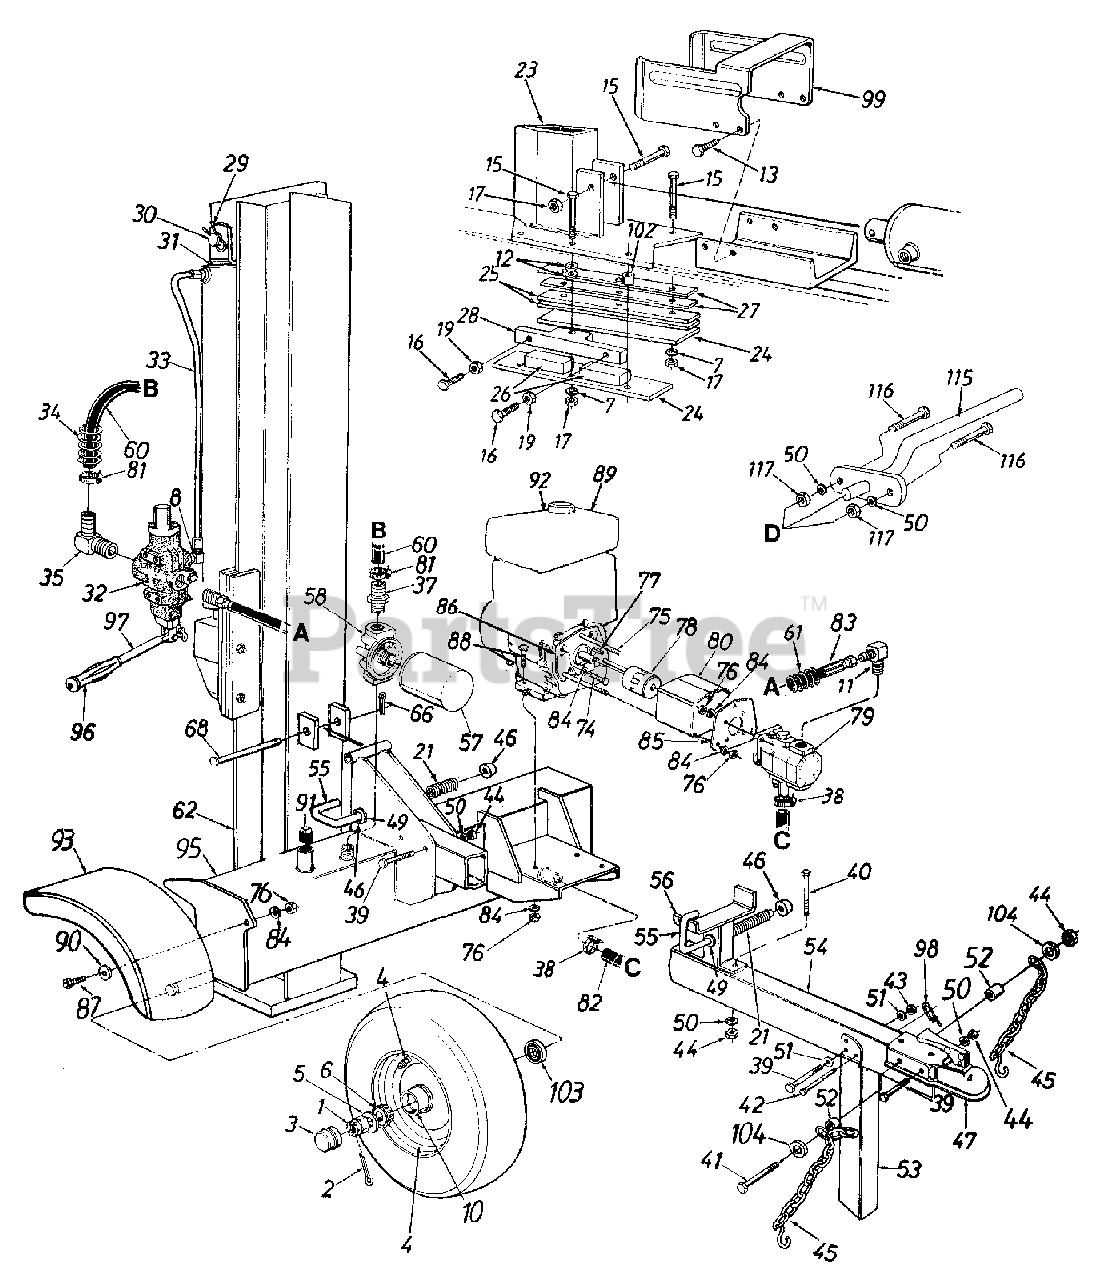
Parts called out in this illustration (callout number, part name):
1	Slotted Nut 3/4-16 Thd.
2	Cotter Pin 5/32" Dia.
3	Hub Cap
5	Fl-Wash. .76" I.D. x 1.5" O.D.
6	Bearing Cone
7	L-Wash. 1/2" I.D.
8	90 degree Solid Male Adapter
10	Bearing Cup
11	90 degree Male Adapter
12	Fl-Wash. .531" I.D. x .94" O.D.
13	Hex Cap Scr. 3/8-16 x 1" Lg.
15	Hex Bolt 1/2-20 x 2.75" Lg.
16	Hex Bolt 3/8-24 x 1.5" Lg.
17	Hex L-Nut 1/2-20 Thd.
19	Hex Jam Nut 3/8-24 Thd.(Grade 5)
21	Comp. Spring 4" Lg.
29	Cotter Pin
30	Clevis Pin
31	Kit Seal 5.0" for Best Metals cylinder 718-0313
31	Hydraulic Cylinder
31	Kit Seal 5.0" for XINGHUI cylinder 718-0313A
31	Kit Seal 5.0" for ENERGY cylinder 718-0313A
33	Metal Pressure Tube
34	Hose Guard
35	Return Elbow
37	3/4" Hose Barb.
38	Hose Clamp 1.5" O.D.
39	Hex Bolt 3/8-16 x 3" Lg. (Grade 8)
40	Hex Bolt 3/8-16 x 4" Lg.
41	Hex Bolt 3/8-16 x 4.25" Lg.
42	Clevis Pin 5/16 x 2.5" Lg.
43	Hex L-Nut 3/8-16 Thd.
44	Hex Nut 3/8-16 Thd.
45	Chain-Tow Hitch
46	Push Cap
47	Hitch Coupler
49	Fl-Wash. .635" I.D. x .93" O.D.
50	L-Wash. 3/8" I.D.
51	Fl-Wash. .406" I.D. x .75" O.D.
52	Spacer .445" Lg.
55	Locking Rod
57	Filter Element
58	Filter Head
60	Return Hose 3/4" I.D. x 44" Lg.
61	Hose Guard
68	Hinge Pin 1/2 x 4.8" Lg.
74	Hex Bolt 5/16-24 x .62" Lg.
75	Hex Bolt 5/16-24 x 5.25" Lg.
76	Hex Nut 5/16-24 Thd.
77	Sq.-Key 1/4" x 2" Lg.
78	Flexible Coupling
79	Gear Pump
80	Coupling Shield
81	Hose Clamp 5/8"
82	Suction Hose 1" I.D.
83	High Pressure Hydraulic Hose 48"
84	L-Wash. 5/16" I.D.
87	Hex Bolt 5/16-24 x .75" Lg.
88	Hex Bolt 5/16-24 x 1.75" Lg.
89	Engine
90	Fl-Wash. .344" I.D. x .875" O.D.
91	L-Vent Pipe Plug
92	Spark Plug Boot
97	Control Handle
98	Spring Pin
102	Spacer 1/2" I.D. x .86" Lg.
103	Bearing Seal Only
104	Fl-Wash. 3/8" I.D. x .87" O.D.
117	Hex Nut 3/8 - 16 Thd.
